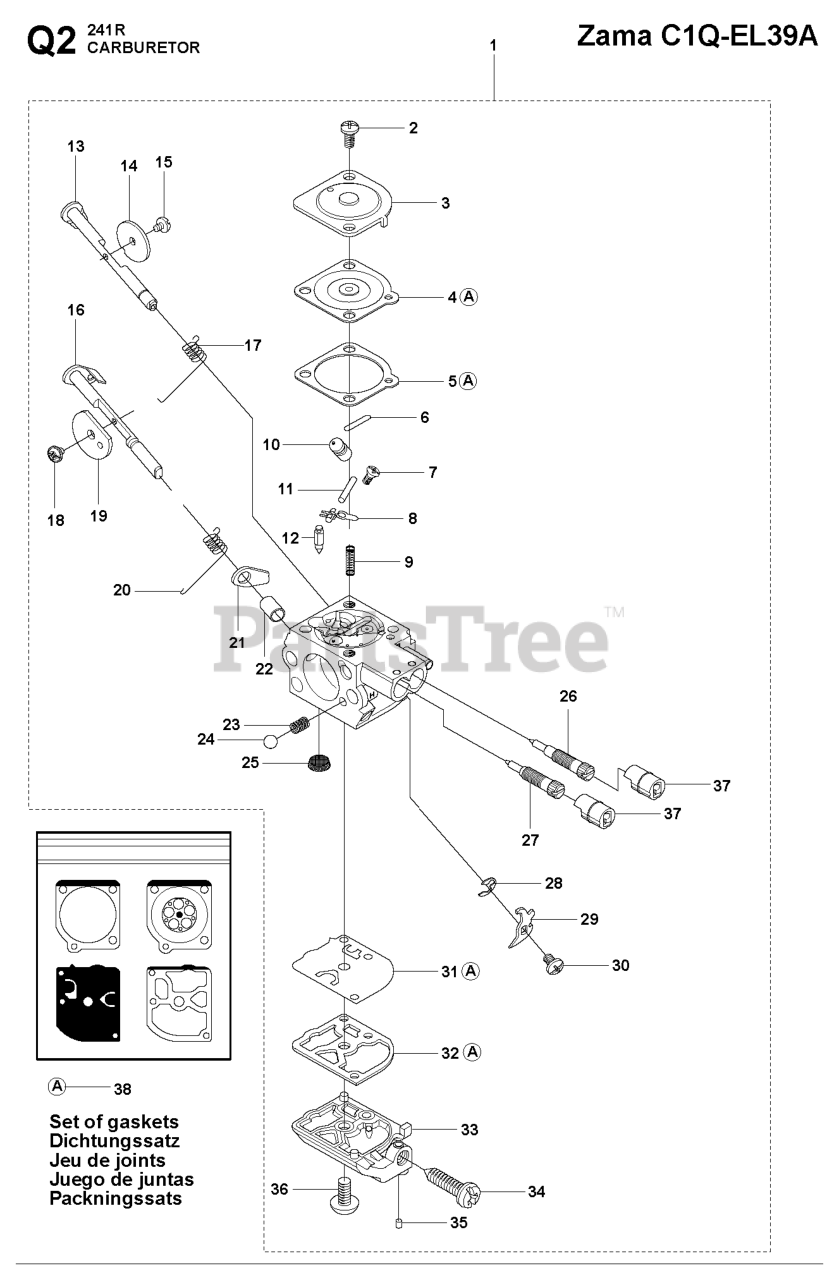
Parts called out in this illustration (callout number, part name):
1	CARBURETTOR C1Q-EL39A
9	SPRING
11	PIN RETAINING SCREW
12	INLET NEEDLE
13	SHAFT ASSY
16	SHAFT ASSY
17	RETURN SPRING
25	FUEL INLET SCREEN
26	SCREW IDLE MIXTURE
27	SCREW MAIN MIXTURE
28	CLIP
31	PUMP DIAPHRAGM
37	LIMITER CAP KIT
38	GASKET KIT (ZAMA GND39)
